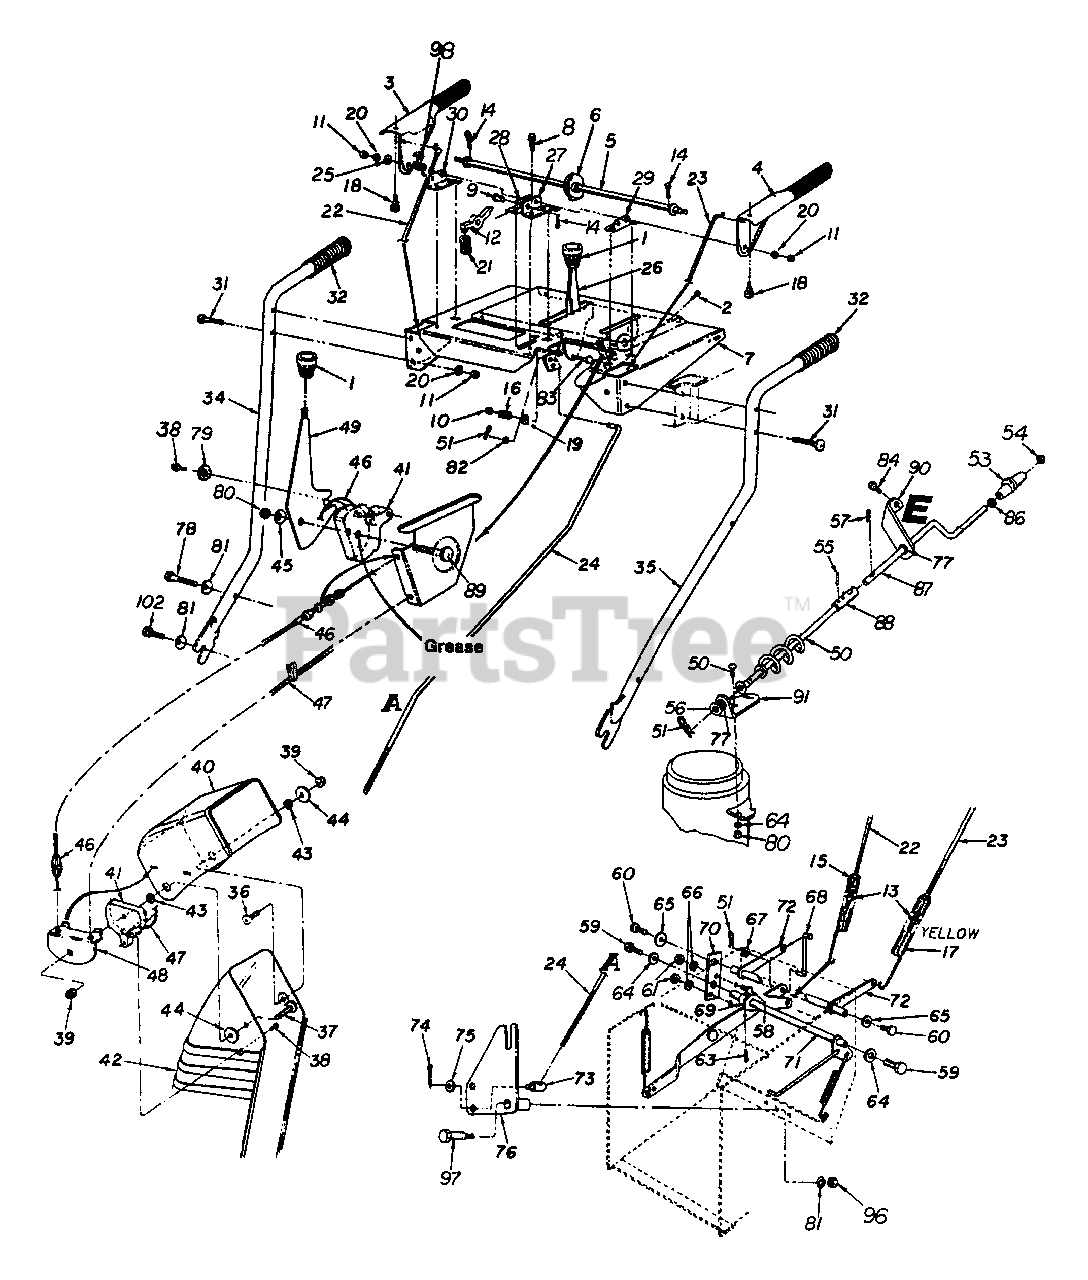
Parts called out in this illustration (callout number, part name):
1	Ball Knob
2	Pan Head B-Tapp Scr. #10 x .50
3	Engagement Handle R.H. Black
4	Engagement Handle L.H. Black
5	Cam Rod
6	Clutch Lock Cam
9	Clevis Pin .81 Dia. x 1.0" Lg.
10	Hex Nut 3/8-24
11	Hex Nut 5/16-18
12	Cam Lock Paul
13	Hex Ins. Lock Nut 1/4-20
14	Cotter Pin 3/32 Dia. x 1.00 Lg.
15	Extension Spring
16	Compression Spring .38 I.D. x .88 Lg.
17	Extension Spring .76 O.D. x 5" Lg.
18	Rubber Bumper
19	Bell-Wash. .400 I.D. x .88 O.D. x .06
20	L-Wash. 5/16 I.D.
21	Compression Spring
22	Lockout Cable x 28" Small
23	Lockout Cable x 25" Small
24	Shift Rod 34.25" Lg.
25	Washer (Special)
26	Shift Lever
31	Carriage Blt 5/16-18 x 1.75" Lg.
32	Grip
34	r.H. Handle Black
37	Carriage Bolt 5/16-18 x .175" Lg.
38	Hex Wash. AB-Tap Scr. 1/4 x .62" Lg.
39	Hex Insert L-Nut 5/16-18
40	Upper Chute Remote Tilt
41	Cable Guide
42	Lower Chute Remote Tilt
43	Chute Pivot Spacer
44	Fl-Wash. .349 I.D. x .679 O.D. x .063
45	Bell-Wash. .325 I.D. x .930 O.D. x .04
46	Chute Control Cable 66"
47	Chute Control Cable w/Clip
54	Cap Speed Nut 3/8" Rod
55	Serrated Pin
56	Fl-Wash. .406 I.D. x .74 O.D. x .063
57	Int. Cotter Pin
58	Hex Screw 1/4-20 x .62
59	Hex L-Bolt 5/16-18 x .62
60	Hex Scr. 1/4-20 x .50 w/Patch
61	Hex Nut 1/4-20
63	Roll Pin 3/16- x 1.25
64	Fl-Wash. .344 I.D. x .875 O.D.
65	Fl-Wash. .25 I.D. x .93 O.D. x .125
66	L-Wash. 1/4 I.D.
67	Fl-Wash. .281 I.D. x .62 O.D. x .051
68	"L" Rod .25 Dia. x 4.70" Lg.
69	Drive Clutch Brkt. 627 R.H. Ass'y.
70	Rivot Bracket .63 Hole
71	Drive Clutch Shaft Ass'y.
72	Pivot Cross Shaft Ass'y.
73	Adjustment Ferrule
74	Cotter Pin 3/32 x .75
75	Fl-Wash. .344 I.D. x .625 O.D. x .063
78	Hex Screw 3/8-16 x 1.75
79	Contour Washer
80	Hex Cent. L-Nut 5/16-18
81	Bell-Wash. .400 I.D. x .88 O.D. x .05
82	Fl-Wash. .344 I.D. x .625 O.D. x .063
83	Hex Cap Scr. 3/8-24 x 1.5
84	Hex Scr. 1/4-20 x .75
86	Flat Washer
88	Spacer 3/8 I.D. x 12.5
89	Hex Cap Screw 5/16-18 x 1.25
97	Shoulder Screw .498 x 2.00
98	Torsion Spring
